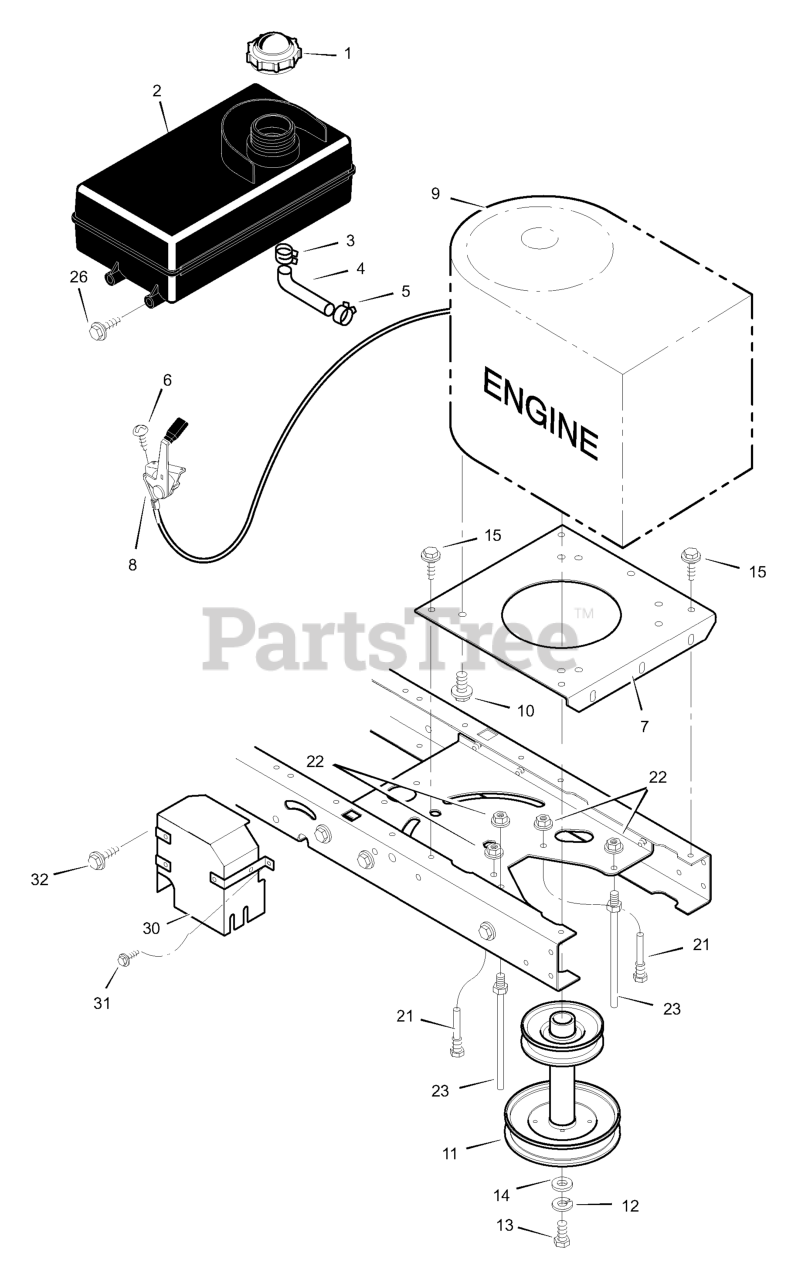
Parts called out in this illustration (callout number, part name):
1	Fuel Cap
2	TANK, Fuel 1.4 Gal.
3	Hose Clamp
4	Fuel Line
5	Hose Clamp
7	Plate, Engine
8	Throttle Control
9	Engine
10	Bolt, Engine Mount
11	STACK PULLEY ASSEMBLY
12	Lockwasher
13	Bolt, Hex
21	Guide, Belt
22	Nut, Flange
23	Guide, Belt
30	Shield, Heat
